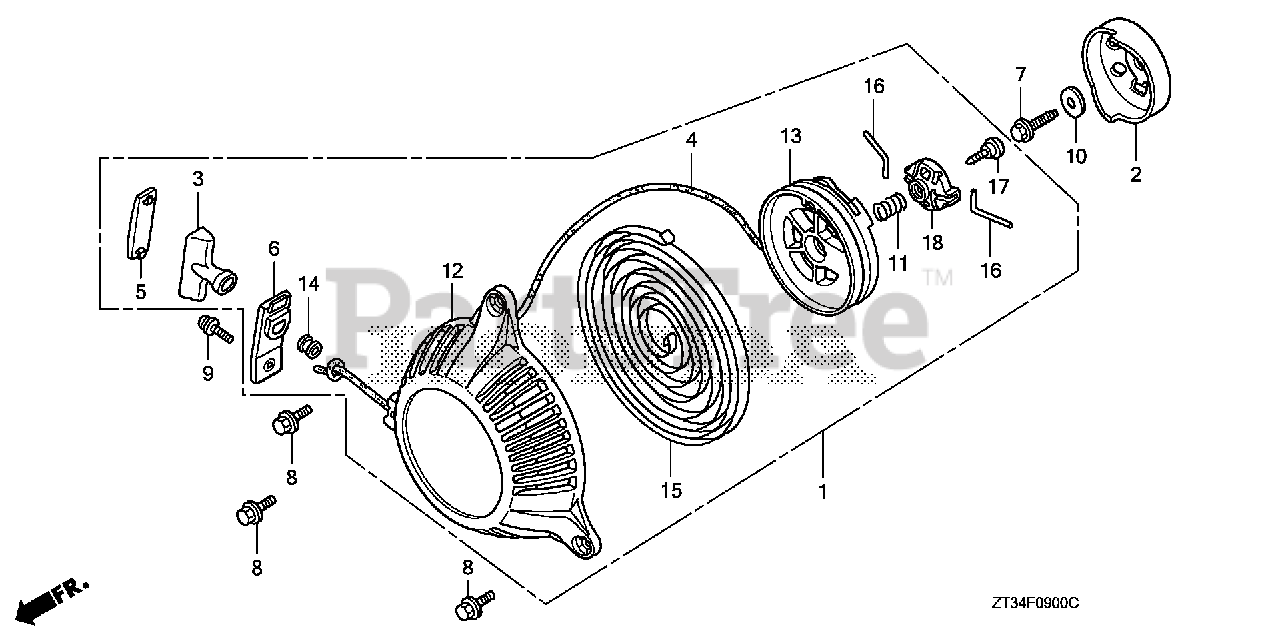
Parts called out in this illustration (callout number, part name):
1	STARTER ASSY., RECOIL
2	PULLEY, RECOIL STARTER
3	GRIP, STARTER
4	ROPE, RECOIL STARTER
5	COVER, GRIP
6	GUIDE, STARTER ROPE
7	BOLT, FLANGE (6X16) (CT200)
8	BOLT, FLANGE (5X10)
9	SCREW-WASHER (5X10)
10	WASHER, PLAIN (6MM)
11	SPRING, FRICTION
12	CASE, RECOIL STARTER
13	REEL, RECOIL STARTER
14	GUIDE, ROPE
15	SPRING, RECOIL STARTER
17	SCREW, SETTING
